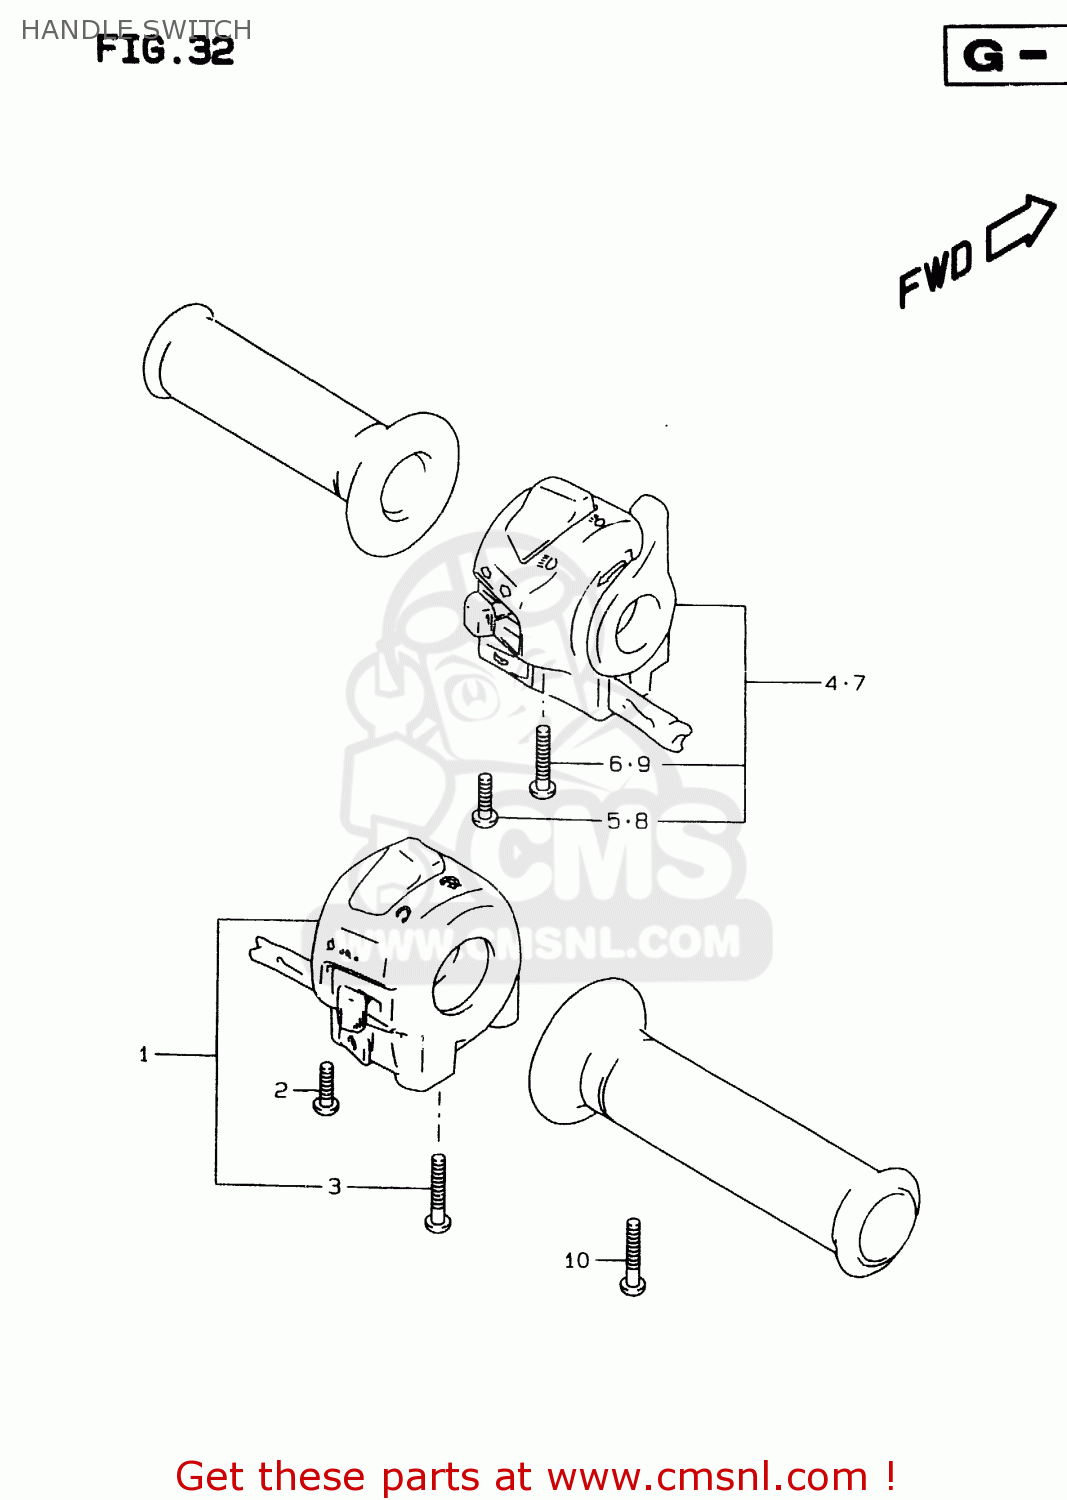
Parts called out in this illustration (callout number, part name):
1	SWITCH ASSY,HANDLE,R
2	SCREW
3	SCREW
4	SWITCH,HANDLE,
5	SCREW
6	SCREW
7	SWITCH ASSY,HANDLE,L
8	SCREW
9	SCREW, 5X45
10	SCREW
